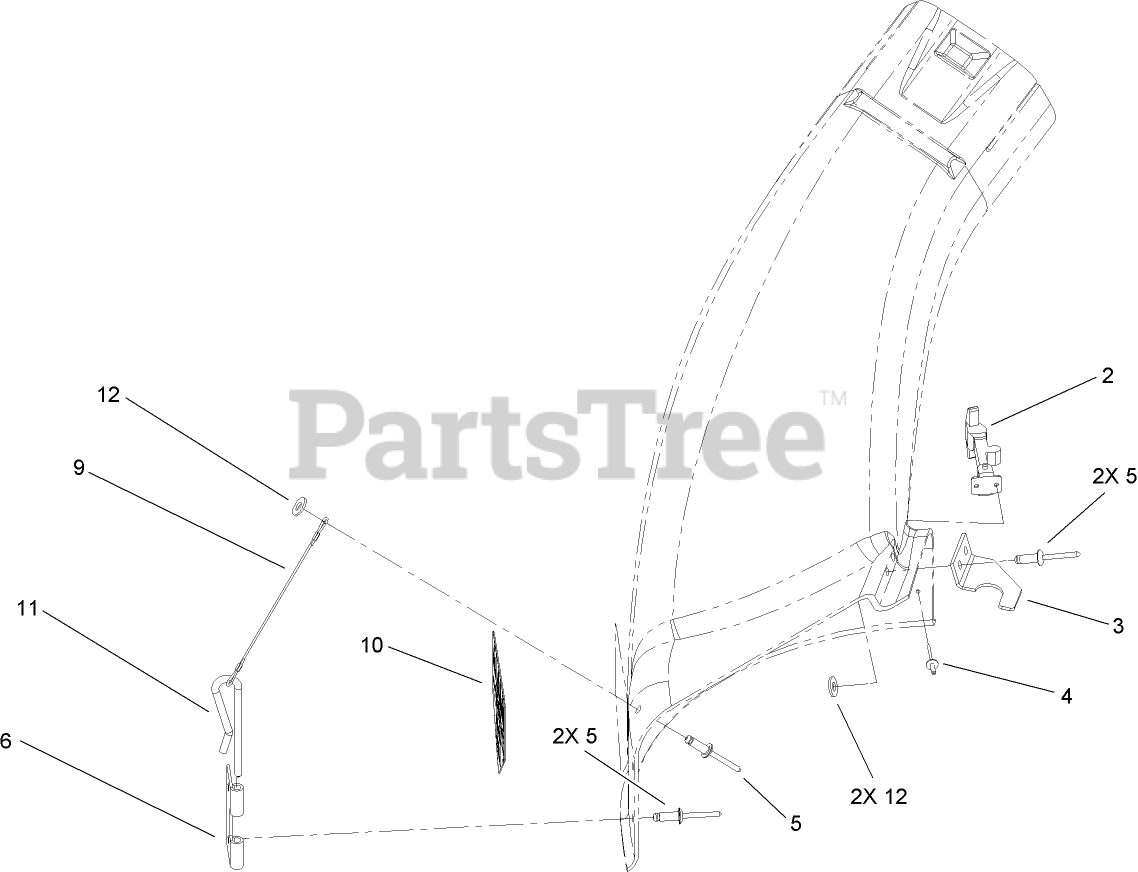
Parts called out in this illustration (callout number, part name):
2	HANDLE ASM
3	LATCH-ELBOW, BAGGER
4	RIVET-POP
5	RIVET-BLIND
6	BRACKET-MOUNTING, CHUTE
9	LANYARD
10	DECAL-DANGER, SHIELD
11	PIN-LOCKING, CHUTE
12	WASHER-FLAT
